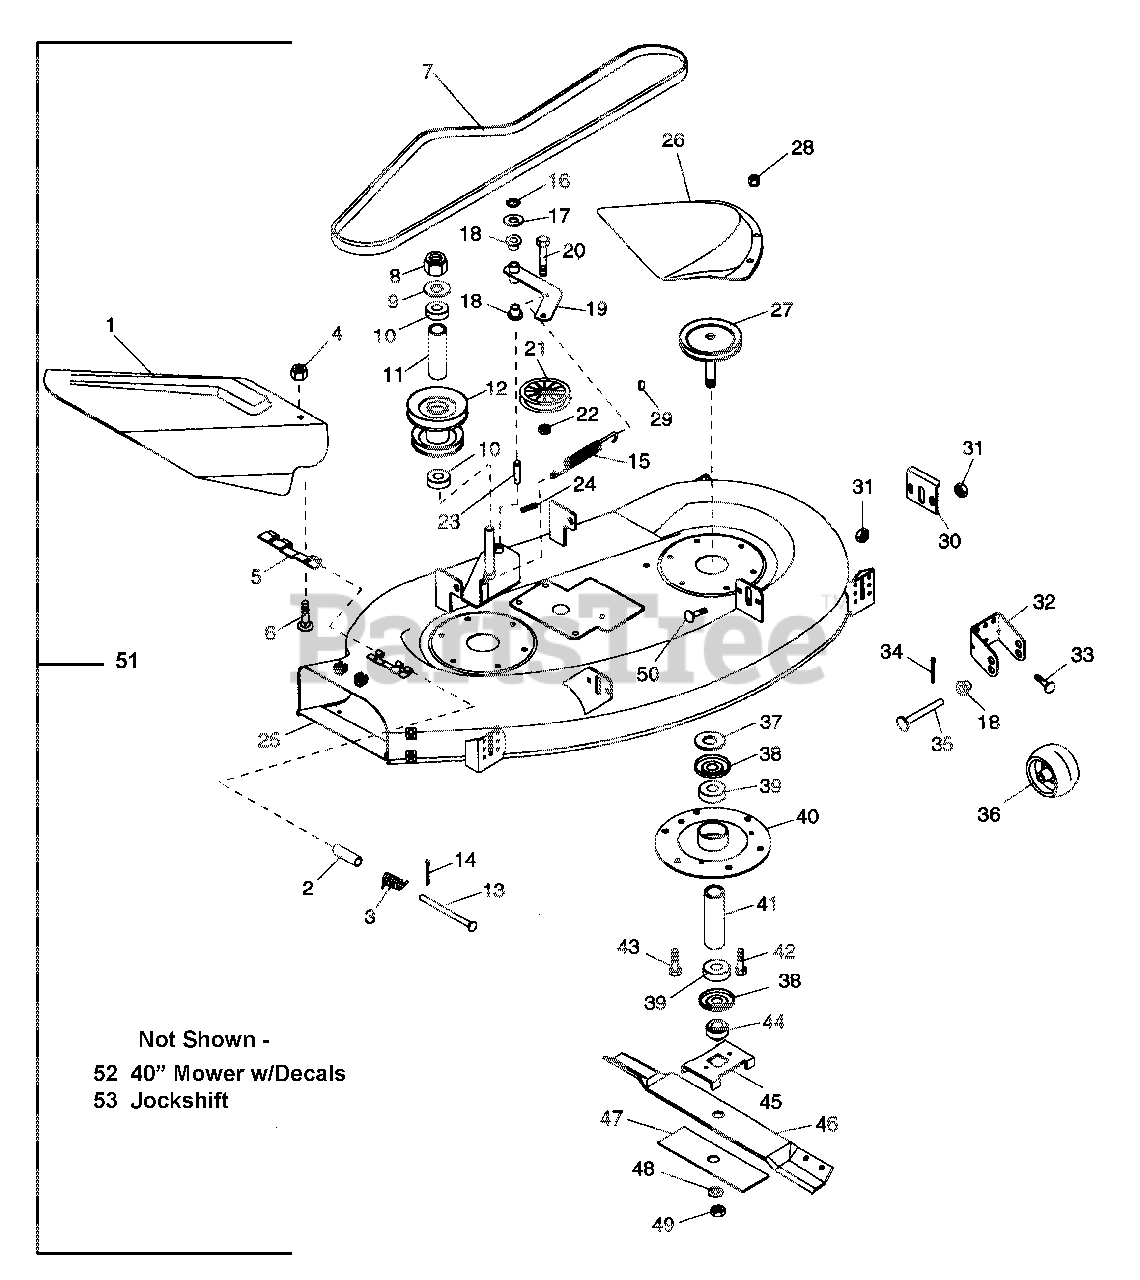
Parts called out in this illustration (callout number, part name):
1	40IN. CHUTE DEFLECTOR
2	BSHG-SLV .334 X .502 X 1.437
3	SG-TORS .095X.50X 1.0
4	NUT-LK-CTR .250-20 PL
5	HINGE PLATE
6	BLT-RDHDSQNK .25-20X.75 GR5PL
7	V-BELT, 4L-WRAPPED
8	NUT-LK-NYL.625-18 PL
9	WSHR-FL-STL .640X1.005X.062 PL
10	BRG-BALL .625X1.375X.44
11	SPACER .640X.880X2.545
12	JACKSHAFT PULLEY
13	CLEVIS PIN
14	PIN-COTR .09X.75 PL
15	SG-TENS .105X.812X3.88 WLD 15
16	RG-RING-EXT .375X.025
17	WSHR-FL-STL.406X.812X.065PL
18	BSHG-FLG .372X.500X.312X.625NY
19	IDLER ARM
20	BLT-HEX .38-16X1.50 PL GR5
21	IDLER-FLAT 3.00X.38
22	NUT-LK TOP .375-16 GR C YWZC
24	PIN-ROLL .125X.63
25	40" PAN WELDMENT
27	L. SPINDLE SHEAVE
27	R. SPINDLE SHEAVE
28	NUT-LK-CTR .375-16 GR A PL
29	KEY-WDRF .188X.75X.313 SAE 9
30	MOWER ADJUSTMENT TAB
31	NUT-FLG. .312-18 PL
32	ROLLER CLEVIS
33	BLT-RDHDSQNK .312-18X.62SHTPL
34	PIN-COTR .15 X 1.0 PL
35	PIN-CLEV .371X3.25 YWZC
37	WSHR-FL-STL .755X1.250X.125
38	BEARING SLINGER
39	BRG-BALL .750X1.781X.61
40	SPINDLE HOUSING
41	SPACER .753X1.000X1.140
42	BLT-HEX .38-16X.75 PL GR5
43	BLT-HEX .38-16X1.00 PL GR5
44	RETAINER HUB
45	BLADE TRAY 48
46	MOWER BLADE
48	WSHR-LK .750X.188 MED PL
49	NUT-JAM .75-10 PL
50	BLT-RDHDSQNK.31-18X.75GR5SHTPL
51	40" MOWER DECK ASSY COMPLETE
